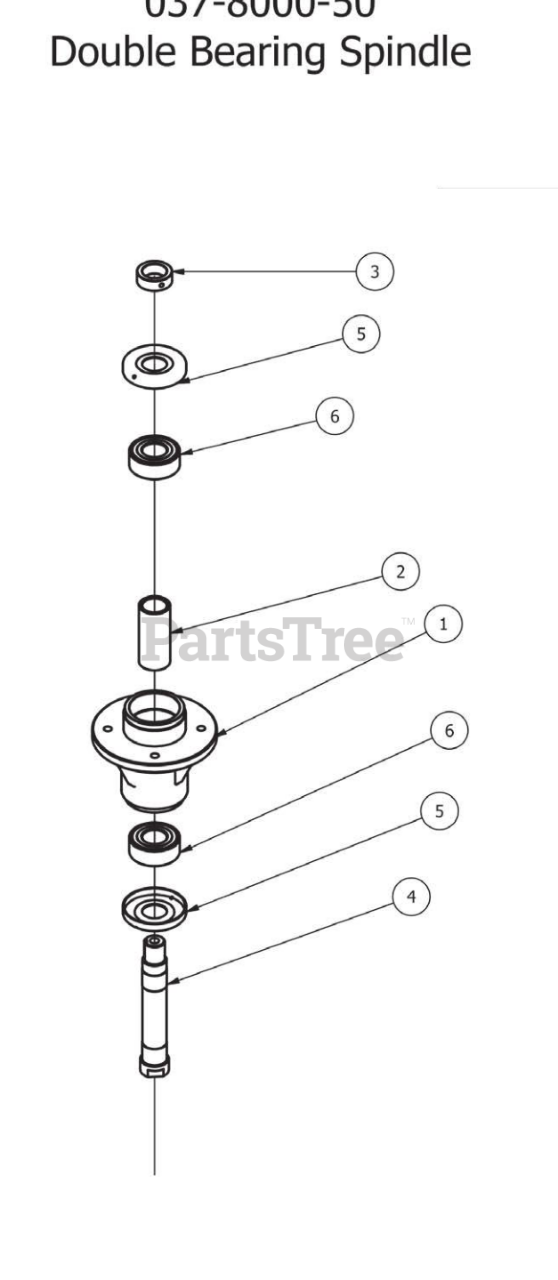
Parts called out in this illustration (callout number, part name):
1	Aluminum Spindle Housing
2	Tube Spacer Double Bearing Spindle
3	Collar Spacer - Top of Spindle
4	Short Spindle Shaft w/Locking
5	Dust Cover
6	Double Bearing for spindle
